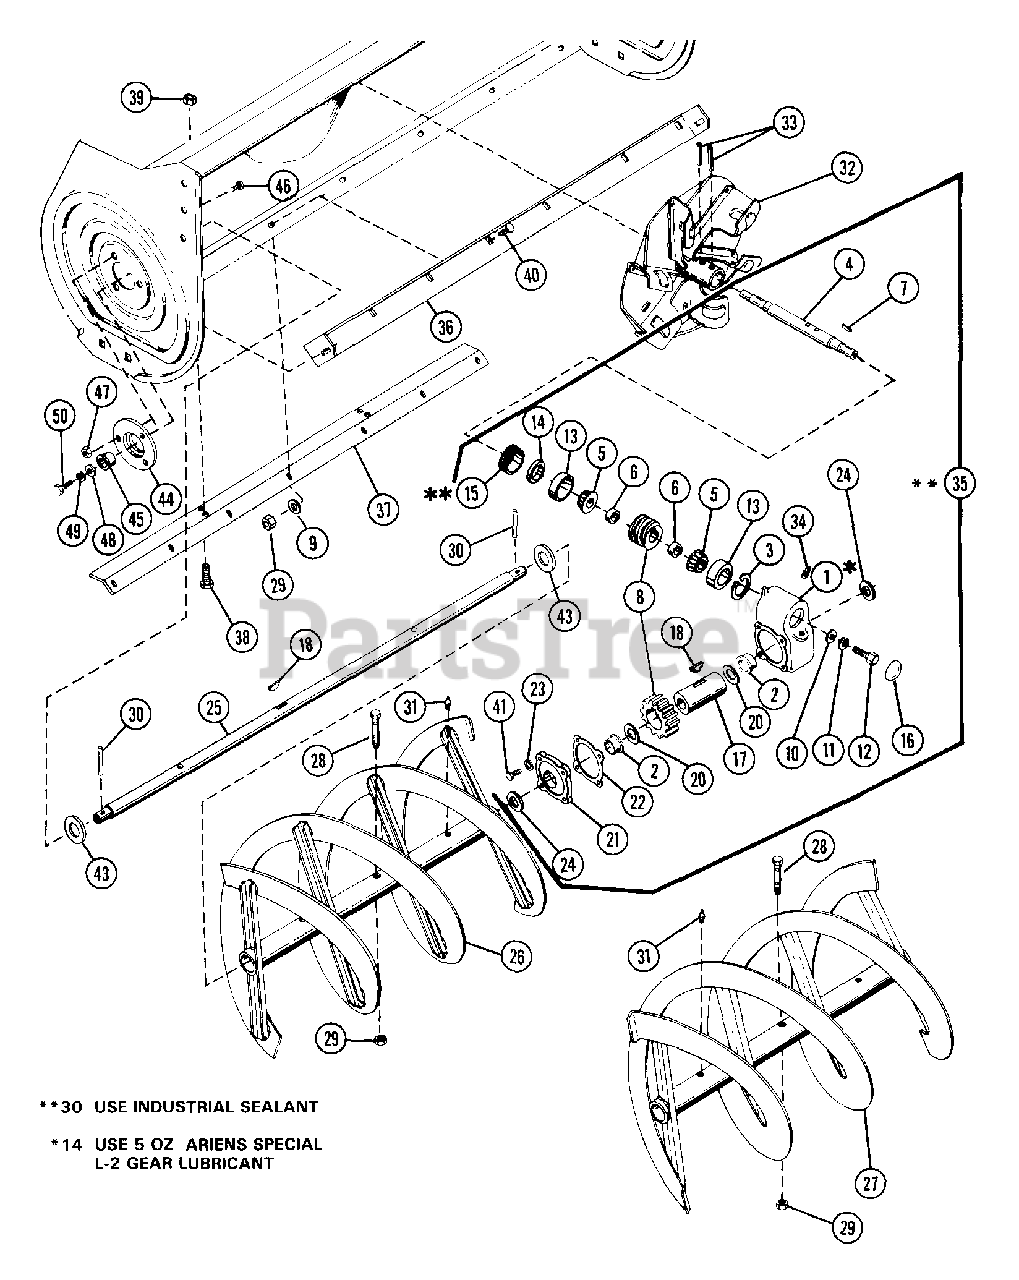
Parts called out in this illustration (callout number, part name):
1	V-BELT, 4L-RAW EDGE
1	SUPPORT
1	GEAR CASE - CAST IRON
2	NUT-LK-CTR .50-13
2	PUSH FRAME
2	BSHG-FLG .683X1.87X1.68X2.250
3	IDLER-FLAT 2.75X.62
4	BSHG-FLG .500X.625X.500X.750
4	PIN-COTR .18X1.0 PL
4	WORM SHAFT
5	WSHR-FL-STL .505X.880X.072 PL
5	LATCH PIN
5	BRG-CONE .750X.61
6	SG-COMP .080X.85X1.44
6	BSHG, SPCR .755X1.12X.50 PM
7	BLT-HEX .50-13X1.25 PL GR2
7	PIN-COTR .12X1.0 PL
7	KEY-SQ .188X1.0X.188 SAE 8630
8	SHOULDER BOLT
8	BLT-HEX .31-18X1.25 PL GR2
8	WORM & GEAR SERVICE ASSEMBLY
9	SG-TENS .091X.73X5.28 WLD 30
9	NUT-LK .312-18 GR A PL
9	WSHR-FL-STL .38X.875X.083 PL
10	38 INCH MOWER PAN W/DECALS
10	WSHR-FL-STL .328X1.0X.094
11	NUT-LK-CTR .375-16 GR A PL
11	BLT-RDHDSQNK .312-18X.62SHTPL
11	WSHR-LK .312X.097 PL HVY
12	PIVOT PLATE
12	BLT-HEX .31-18X.75 PL GR2
13	WSHR-FL-STL .755X1.250X.125
13	BLT-HEX .38-16X1.00 PL
13	BRG-CUP 1.781X.475
14	BEARING SLINGER
14	SPACER .406X.749X.162
14	SEAL 1.000X1.312X.150
15	BRG-BALL .750X1.781X.61
15	WSHR-FL-STL .438X1.0X.083 PL
15	ADJUSTMENT PLUG - 1" SHAFT
16	SPINDLE HOUSING
16	NUT-HEX .375-16
16	DUST CAP
17	SPACER .753X1.000X1.140
17	GEAR CASE SHAFT
18	KEY-WDRF .188X.75X.313 SAE 9
18	PIN-COTR .12X.75 PL
18	KEY-WDRF .25X.875X.375 SAE A
19	RETAINER HUB
20	BLADE TRAY
20	UNIVERSAL BLOCK JOINT
20	WSHR-FL-STL 1.625X2.500X.012
21	MOWER BLADE
21	GEAR CASE COVER
22	SHEAVE
22	CHANNEL
23	BLT-HEX .38-16X1.00 PL
23	STIFFENER PLATE
23	WSHR-LK-EXT. 250 ID
24	BLT-HEX .38-16X.75 PL GR2
24	BLT-HEX .31-18X2.50 PL GR5
24	SEAL 1.625X2.125X.250
25	CAP, GREASE
25	WSHR-LK .312X.097 PL HVY
25	SHAFT, 36" RAKE - 1.00 DIA.
26	NUT-JAM SL .75-20 PL
26	WSHR-FL-STL .323X.625X.062 PL
26	RAKE, RIGHT-36"(1ID X 15.75OD)
27	PIN-COTR .12 X 1.25 PL
27	NUT-HEX .312-18
27	RAKE, LEFT-36"(1"ID X 15.75OD)
28	BRG-CONE .750X.61
28	WELDMENT, SNOW BLADE
28	SHEAR BOLT SERVICE ASSEMBLY
29	BRG-CUP 1.781X.475
29	WEAR PLATE
29	NUT-LK .312-18 GR A PL
30	SHEAVE 38 IN PAN
30	BLT-RDHDSQNK .31-18X1.00 PL
30	PIN-ROLL .188X1.50
31	SPACER .753X1.000X.625
31	WSHR-FL-STL .38X.875X.083 PL
31	SPIN DRIVE ZERK FITTING
32	SKID SHOE
32	FAN - 14"
33	BLT-RDHDSQNK .38-16X.75 SHT PL
33	BLT-RDHDSQNK .38-16X1.0 PL
33	PIN-ROLL .313X1.75
34	WSHR-LK .375X.094 MED PL
34	PIPE PLUG
35	GEAR CASE - 40" - CAST IRON
36	SG-TENS .187X1.50X9.94 WLD 40
36	SCRAPER BLADE 36"
37	TOW PIN
37	MOUNT ROD
37	BLADE BRACE
38	PIN-HAIR INT .09X.188 PL
38	PIVOT SUPPORT
38	BLT-HEX .38-16X.75 PL GR5
39	MOWER STRAP
39	PIVOT ROD
39	NUT-LK TOP .375-16 GR C YWZC
40	NUT-JAM .50-13 PL
40	LIFT BELLCRANK
40	BLT-RDHDSQNK .31-18X.75 GR5 PL
41	LIFT LINK
41	BLT-HEX .25-20X.75 PL GR2
42	LIFT STRAP
43	CHUTE DEFLECTOR UNIT
43	WSHR-FL-STL .531X1.062X.095 PL
43	WSHR-FL-STL 1.010X1.505X.062PL
44	CLEVIS PIN
44	PIN-HAIR INT .09X.188 PL
44	BEARING SUPPORT
45	SG-TORS .095X.50X 1.0
45	WSHR-FL-STL.656X1.312X.095 PL
45	BSHG-FLG 1.000X1.12X.62X1.50BR
46	BSHG-SLV .334 X .502 X 1.437
46	PIN-CLEV .494X1.25 YWZC
46	SCR-SLTR-SERNK .25-20X.62 PL
47	SPIN DRIVE ZERK FITTING
47	CONTROL ROD
47	NUT-LK-FLG .250-20 PL
48	SG-COMP .091X.950X2.062
48	CONTROL SUPPORT
48	WSHR-FL-STL.312X.734X.065PL
49	SEAL .750X1.690X.153
49	WSHR-LK .500X.151 HVY PL
50	WSHR-LK .312X.097 PL HVY
50	BLT-HEX .50-13X1.00 PL GR2
51	WSHR-LK .750X.188 MED PL
51	NUT-HEX .312-18
52	NUT-JAM .75-10 PL
52	BLT-RDHDSQNK .25-20X1.00 GR5
53	WSHR-LK .250X.077 HVY PL
54	PIN-COTR .09X.75 PL
54	NUT-WING .250-20 YWZC
56	V-BELT, 4L-RAW EDGE
58	BRAKE BAND
59	WSHR-FL-STL .755X1.375X.062 PL
60	PIN-COTR .09X1.0 PL
61	PIN-HAIR INT .08X.38X1.42 YWZC
62	LINK
63	PIN-COTR .06X.50
64	WSHR-FL-STL .323X.625X.062 PL
65	BRAKE ROD
66	PIN-ROLL .125X.75
67	NUT-HEX .312-18
68	SG-COMP .057X.47X1.25
69	BRAKE LEVER
70	HANGER HOOK
71	WSHR-LK .312X.097 PL HVY
72	SPACER -FLANGED .325X.498X.318
73	NUT-JAM .312-18 PL
74	CLEVIS PIN
75	PIN-HAIR INT.06X.25X1.12
76	WSHR-FL-STL.406X.812X.065PL
